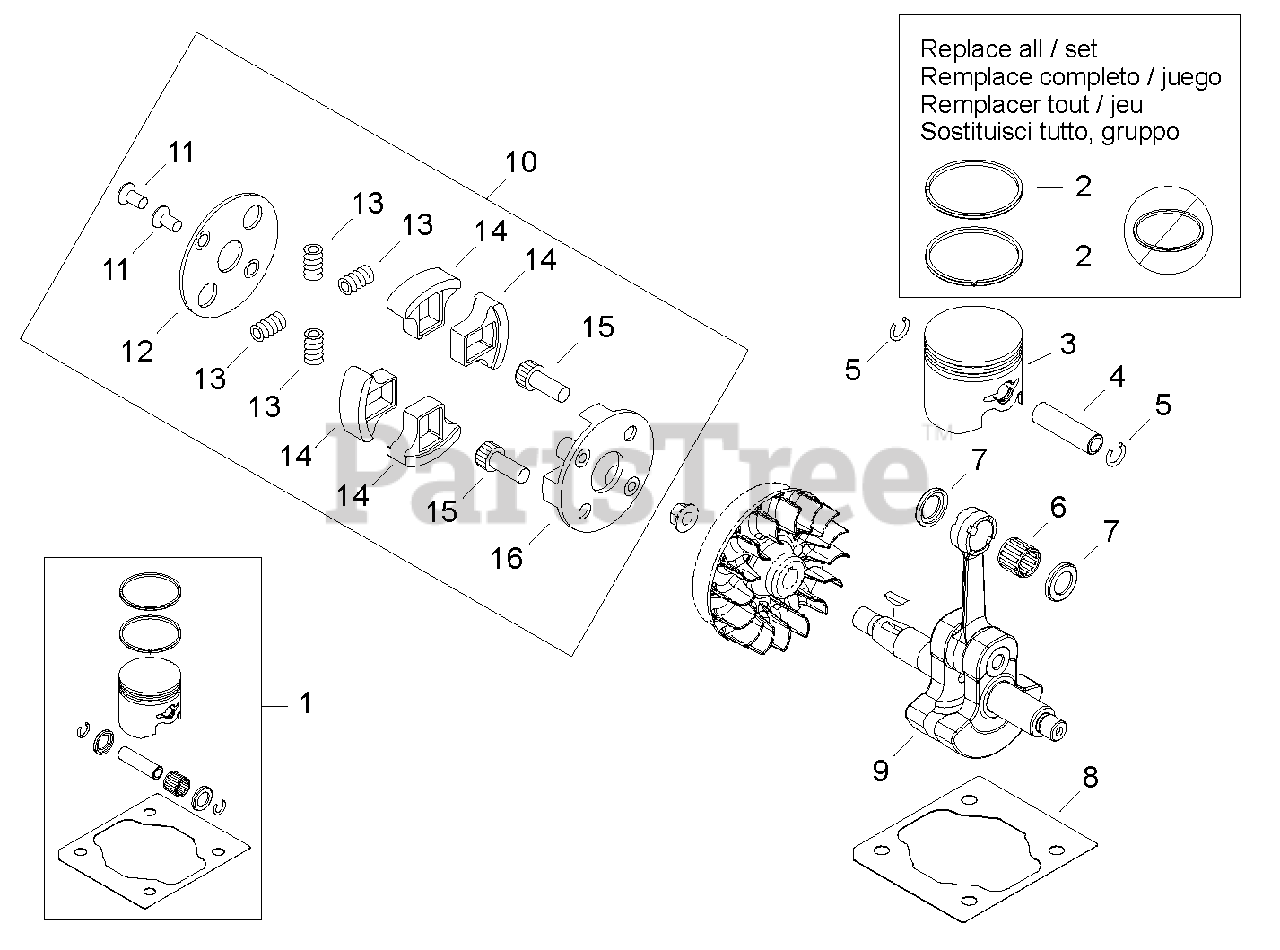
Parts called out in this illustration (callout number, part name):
1	PISTON KIT
2	RING, PISTON
3	PISTON
4	PIN, PISTON
5	RING, RETAINING
6	BEARING, NEEDLE
7	SPACER, PISTON
8	GASKET, CYLINDER
9	CRANKSHAFT ASSY
10	CLUTCH ASSY
11	SCREW
12	PLATE, CLUTCH
13	SPRING, CLUTCH
14	SHOE, CLUTCH
15	BOLT, CLUTCH
16	HUB, CLUTCH
